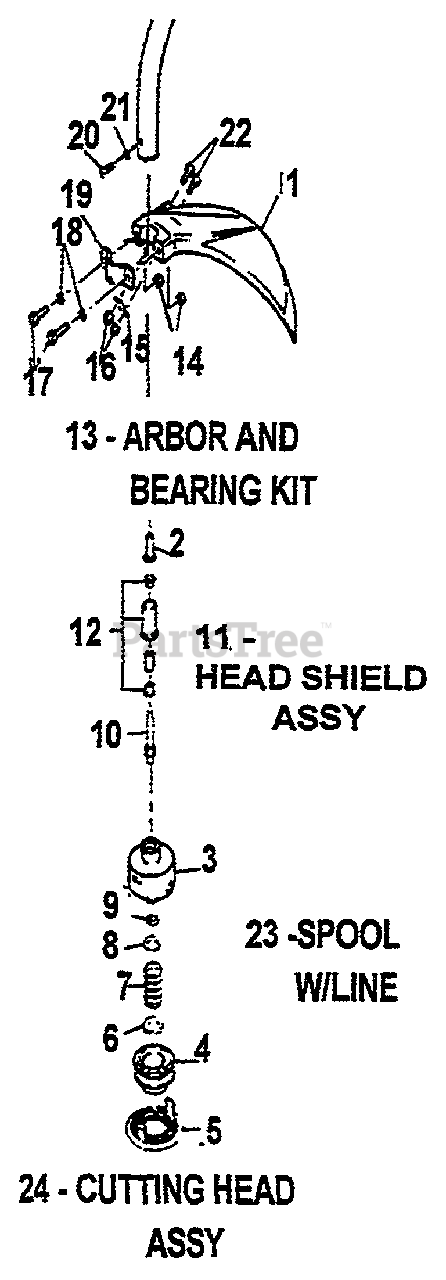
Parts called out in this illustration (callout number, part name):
1	DEFLECTOR
2	ARBOR ADAPTER
3	HEAD BODY
5	CAP
6	SPRING PLATE
7	SPRING
8	SPRING PLATE
10	ARBOR POST
11	HEAD SHIELD ASSY
12	ARBOR BUSH ASSY
13	ARBOR & RING KIT
14	NUT
15	BLADE CUT OFF
19	BRACKET CLAMP
23	SPOOL & LINE
24	HEAD ASSEMBLY
